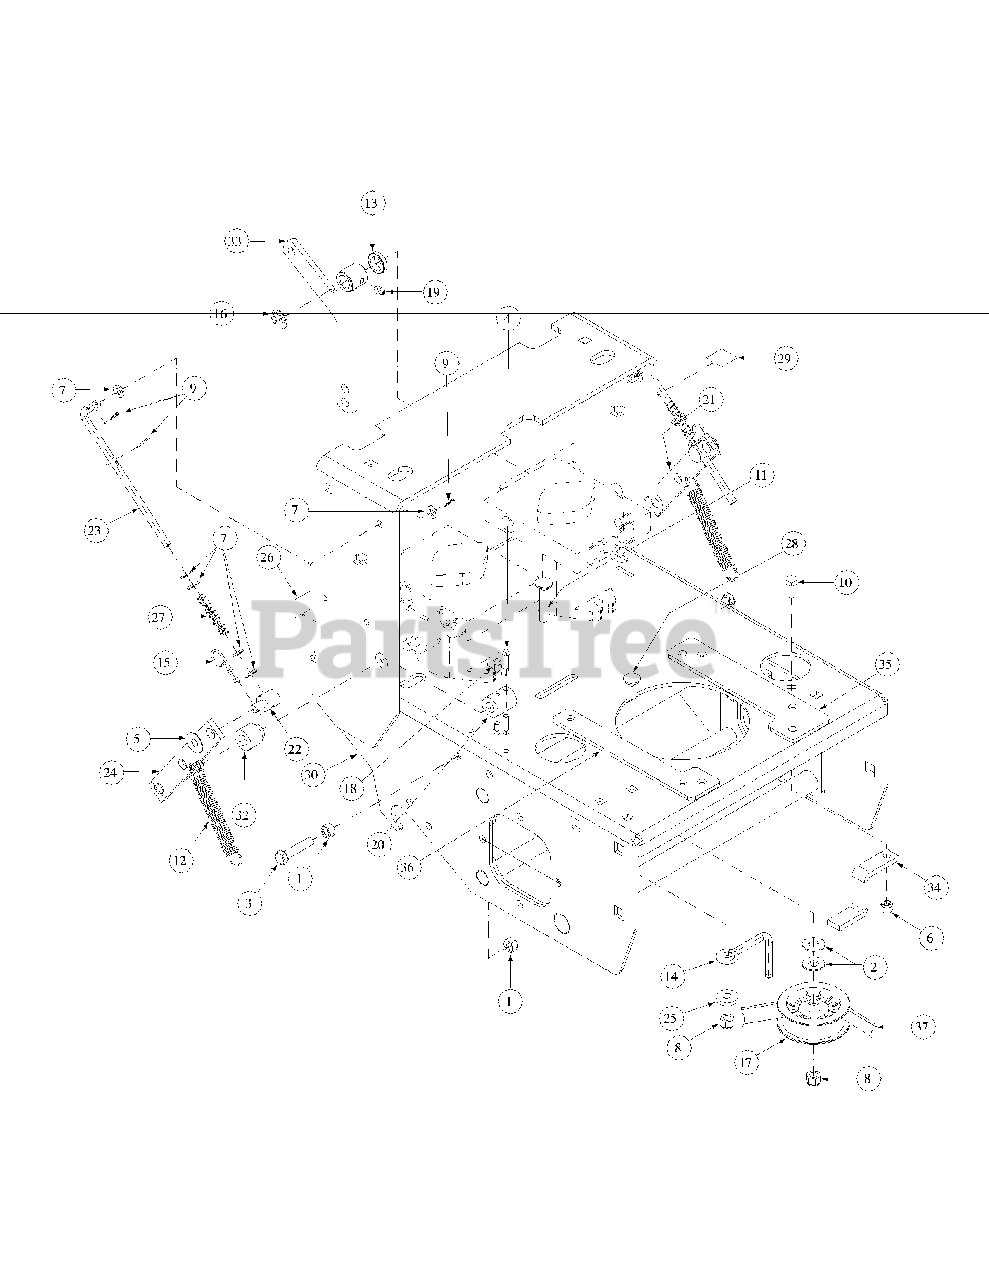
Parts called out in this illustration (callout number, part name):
1	Nut, Hex, 3/8-16 Grade C
2	Flat Washer, USS 3/8 Zinc
3	Cap Screw, 3/8-16 x 1-3/4" Grade 5
4	Cap Screw, Square Head Set, 1/4-20
5	Flat Washer, 3/8, SAE, Zinc/Yellow
6	Nut, 5/16-18, Nylock
7	Flat Washer, SAE Grade 8 5/16, Zinc
8	Nut, L, Nylon Insert, 3/8-16 Grade A
9	Cotter Pin 3/32 x 3/4, Zinc
10	Cap Screw,Standard, 5/16-18 x 1.0, Grade 5
11	Carriage Bolt, 3/8-16 x 2 Grade 5
12	Spring, Music Wire, LE-093G-9, Plated
13	Spacer, Blade Nom, 5/8 ID 1/4 Thick
14	Guide, Traction Drive Belt
15	Pin, Hair 3/8"-1/2"
16	E-Ring, 5/8" #5113-62
17	Pulley, Flat Idler W/Adaptor
18	Screw, Cap, Square Head Set, 1/4-20
19	Grease Fitting, 1/4-28 x 3/16 STR
20	Coupling, Trunnion
21	Hydraulic Pump, Lever Assembly, Left Handle
22	Hydraulic, Pivot
23	Rod, Safety Spring
24	Hydraulic Pump, Lever Assembly, Right Hand
25	Washer, Idler
26	Decal, "Made In America"
27	Spring
28	Carriage Bolt, 3/8-16 x 2 Grade 5
29	Label, Mower, Warn, Open Belt Drive
30	Engine Base Assembly, Hydro
32	Bushing, Pump Lever,
33	Bellcrank Clutch
34	Belt Guide, Engine, 36/42/48
35	Spacer, Engine, Left Hand
36	Spacer, Engine, Right Hand
